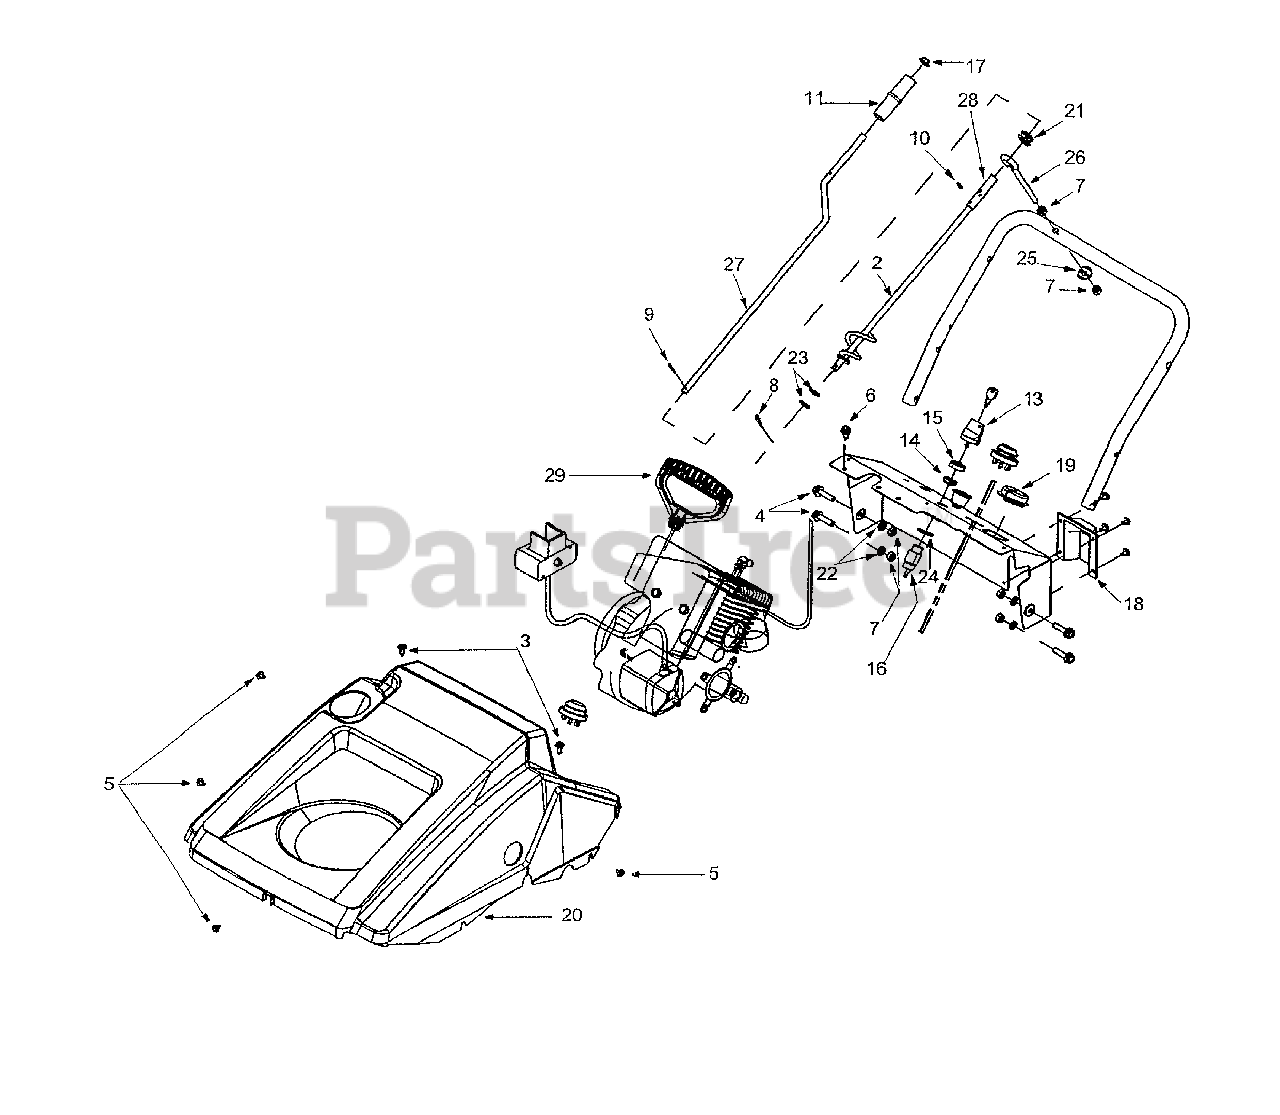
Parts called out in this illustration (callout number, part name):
4	Hex Flange Screw 5/16-18 x 1.25"
5	Special screw
6	Self-Tapping Screw 1/4-20 x .625"
7	Hex Nut 5/16-18
8	Hairpin Clip
9	Cotter Pin
10	Roll Pin
11	Chute Crank Knob
13	Ignition Key w/o Logo
14	Ignition Switch Nut
15	Ignition Switch Cap
16	Switch: Key, Recoil Start
18	Choke Cover
19	Spilling Cup
20	Shroud: 21" Beige
21	Rubber Grommet
22	Lock Washer
23	Flat Washer
24	Internal Lock Washer
25	Saddle Washer
28	Spacer
29	Mitten Grip Handle
